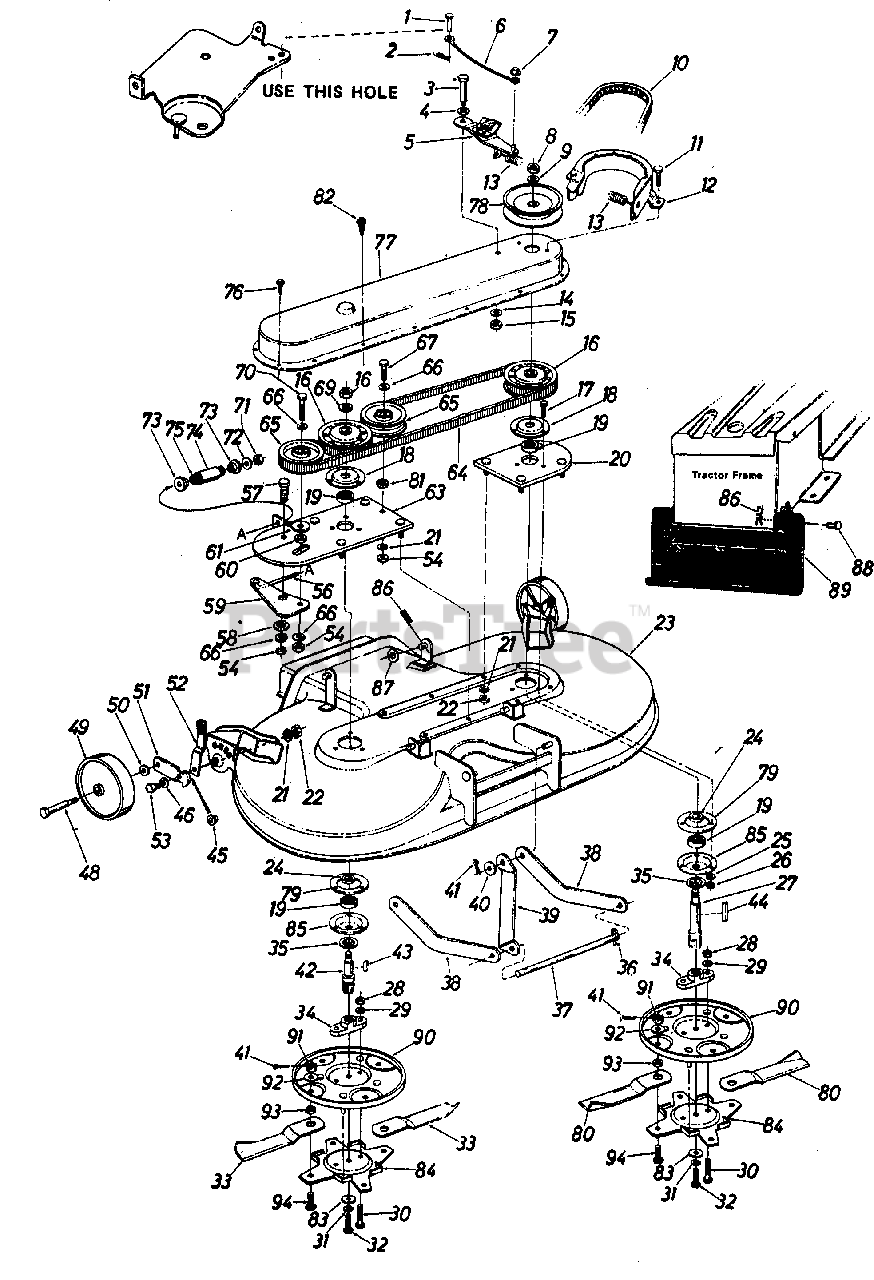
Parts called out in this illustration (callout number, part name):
1	Clevis Pin 1/4" Dia. x 1/2" Lg.
2	Hairpin Cotter 1/4" Dia.
3	Shld. Bolt .437" Dia. x.180" Lg. (5/16-18)
4	WaveWasher 7/16" Scr.
5	Spindle Brake Arm Ass'y.
6	Brake Cable Ass'y.
7	Push Cap 1/4" Stud.
8	Hex Jam Nut 5/8-18 Thd.
9	Bell.-Wash. 5/8" I.D. x 1.25" O.D.
10	"V"-Belt 1/2" x 56" Lg.
11	Hex Wash. Hd. Self Tap Scr. 1/4 20 x .50" Lg.
12	Belt Guard
13	Extension Spring
14	Bell.-Wash 340" I.D.
15	Hex Cent. L-Nut 5/16-18 Thd.
16	Sprocket Pulley Ass'y.
17	Hex Bolt 5/16-24 x 1.00" Lg. (Grade 5)
18	Bearing Housing
19	Ball Bearing.787" I.D. x 1.85" O.D.
20	Spindle Plate Ass'y.
21	L.-Wash. 3/8" I.D.*
22	Hex Jam Nut 3/8-24 Thd.
23	44" R.D. Deck Ass'y.
25	L.-Wash. 5/16" I.D.*
26	Hex Nut 5/16-24 Thd.*
27	Blade Spindle-L.H.
28	Hex Nut 5/16-24Thd.*
29	L.-Wash. 5/16" I.D."
30	Hex Bolt 5/16-24 x 1.00" Lg.
31	L-Wash. 3/8" I.D., H.D.
32	Hex Bolt 3/8-24 x .88" Lg. (Grade 5)
33	Blade-L.H. Rotation
34	Blade Adapter
35	Bearing Shield
36	Hairpin Cotter N
37	Deck Connecting Rod
41	Cotter Pin 3/32" Dia. x 1.00" Lg.*
42	Blade Spindle-R.H.
43	Sq. Key 3/16" x 75" Lg.*
44	Sq. Key 3/16" x 1.50" Lg.*
45	Shoulder Spacer
46	Bell.-Wash 400" I.D.
48	Shld. Bolt 3/8-16 x 1.41" Lg.
49	Wheel Ass'y. Comp. 6" x 1.38
50	Bell-Wash. 3/8" I.D.
51	Wheel Pivot Bar
52	Spring Lever Ass'y. w/ knob
53	Hex Bolt 3/8-24 x 1.25" Lg. Grade 5
54	Hex Cent. L-Nut 3/8-24 Thd.
56	Adjustment Link 5/16-18 x 4-9/16" Lg.
57	Hex Bolt 3/8-24 x 1.00"
58	Shld. Spacer .625" I.D.
59	Belt Idler Brkt.
60	Spacer.380" I.D. x .625" O.D. x .265
61	Fl.-Wash. .38" I.D. x 1.37" O.D. x.125
63	Spindle & Idler Mount Plate Ass'y.
64	HTD Twin Power Belt
65	Fl.-ldler Pulley 3.50" O.D.
66	Bell.-Wash 38" I.D.
67	Hex Bolt 3/8-24 x 1.75" Lg. (Grade 5)
69	Bell.-Wash. 5/8" I.D.
70	Hex Bolt 3/8-24 x 2.00" Lg.
71	Hex Insert L.-Nut 5/16-18 Thd.
72	Fl.-Wash. 344" I.D. x 1.125" O.D. x .125
73	Sh Id. Spacer .625" 1. D.
74	Spacer-Adj. Bolt
75	Compression Spring
76	Hex Wash. Hd. Self Tap. Scr. 1/4-20 x . 50" Lg.
77	Belt Cover
78	Deck Drive Pulley
79	Deck Reinforcement Plate
80	Blade-R.H. Rotation
81	Fl.-Wash. .38" I.D. x 1.00" O.D.
82	Hex Wash. Hd. Self Tap-Scr. 1/4-20 x .75" Lg.
86	Hairpin Cotter
87	Fl.-Wash. 1/2" I.D.
88	Clevis Pin
89	Safety Shield-16 5/8" Lg.
92	Fl.-Wash. .531" I.D. x 1.25" O.D.
93	Spacer
94	Shld. Scr. .50" Dia. x .36"
